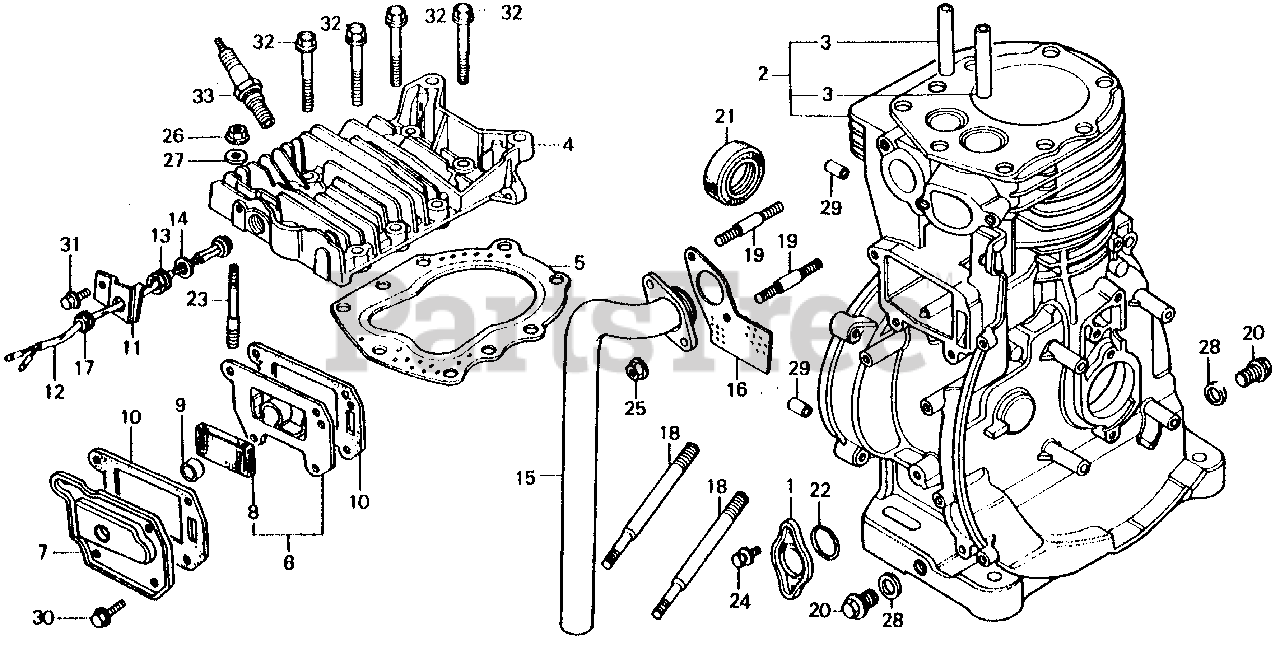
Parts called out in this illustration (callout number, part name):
1	COVER, OIL PAN
2	CYLINDER (CRANKSHAFT P.T.O.)
2	CYLINDER (CRANKSHAFT P.T.O.) (NOT AVAILABLE)
3	GUIDE, VALVE
4	CYLINDER HEAD (NOT AVAILABLE)
5	GASKET, CYLINDER HEAD
6	CASE, BREATHER
7	COVER, TAPPET
8	FILTER, BREATHER
9	SEAL, BREATHER
10	GASKET, TAPPET COVER
11	COVER, THERMOSTAT SWITCH
12	SWITCH ASSY., THERMOSTAT (NOT AVAILABLE)
13	BOSS, THERMOSTAT SWITCH (NOT AVAILABLE)
14	WASHER, SWITCH BOSS
16	GASKET, MUFFLER
17	GROMMET, CABLE
18	BOLT, STUD (8X110)
18	BOLT, STUD (8X104)
19	BOLT, STUD (8X35)
20	BOLT, DRAIN PLUG
21	OIL SEAL (30X46X8)
22	O-RING (27X2.0)
23	BOLT, STUD (10X70)
23	BOLT, STUD (10X60)
23	BOLT, STUD (10X40)
24	BOLT-WASHER (6X12)
25	NUT, FLANGE (8MM)
26	NUT, FLANGE (10MM)
27	WASHER, PLAIN (10MM)
28	WASHER, DRAIN PLUG (12MM)
29	PIN A, DOWEL (8X14)
30	BOLT, FLANGE (6X12)
31	BOLT, FLANGE (8X16)
32	BOLT, FLANGE (10X55)
33	SPARK PLUG (BPR6HS-10) (NGK)
33	SPARK PLUG (W20FPR-U10)
